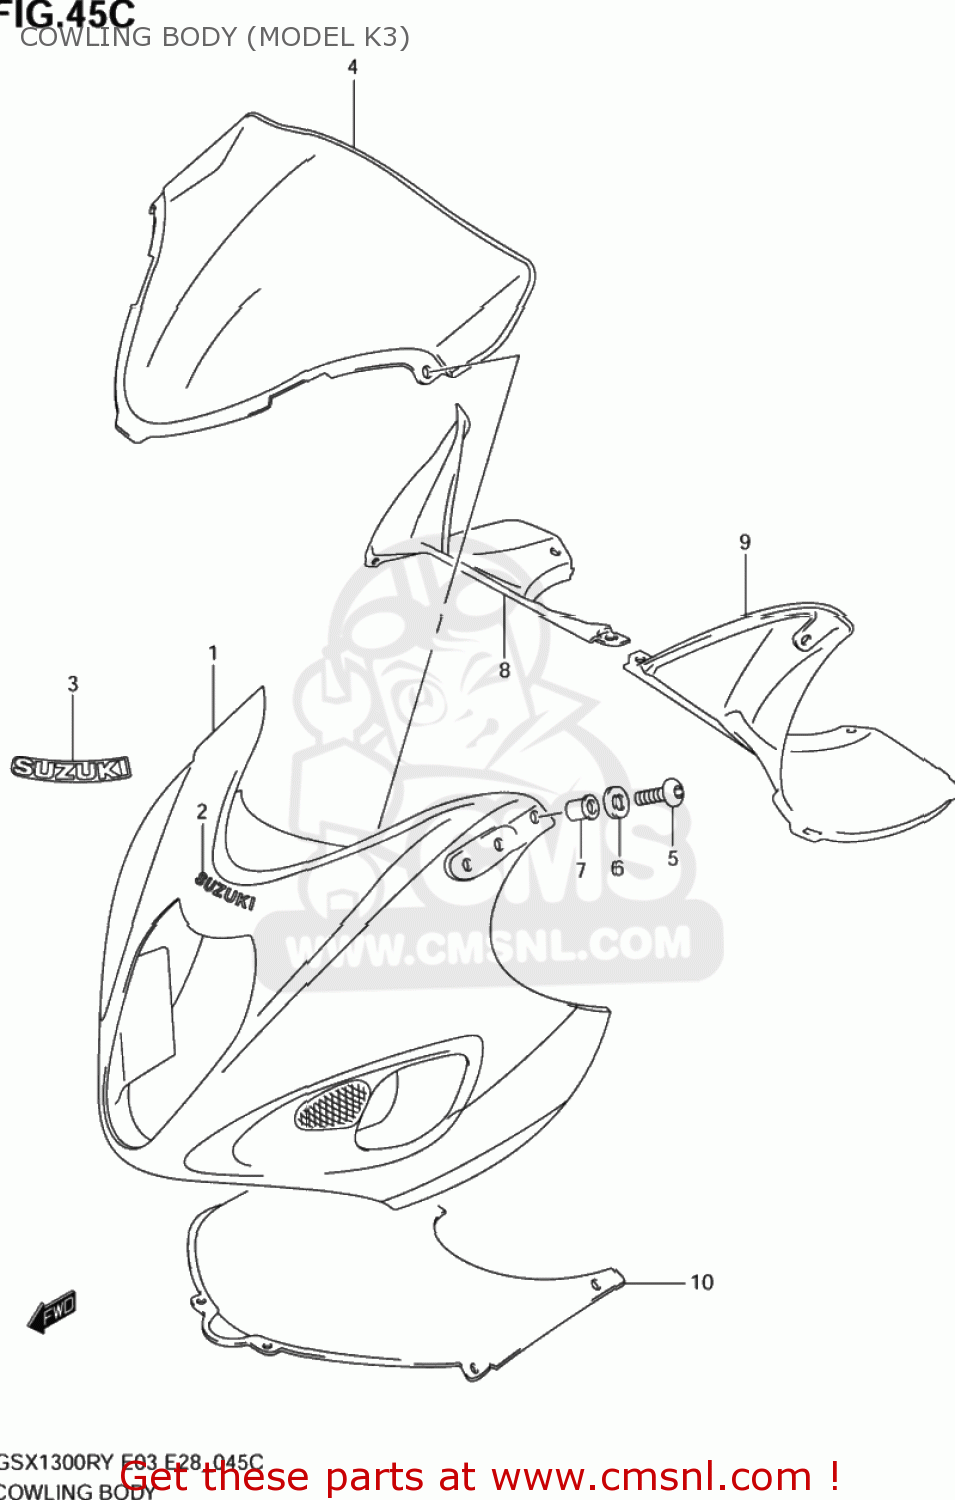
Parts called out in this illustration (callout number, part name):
1	COWLING ASSY,BODY
2	EMBLEM,SUZUKI
3	EMBLEM,SUZUKI
4	WINDSCREEN
5	SCREW(5X14)
6	WASHER
7	NUT
8	PANEL,UPR,R
9	PANEL,UPR,L
10	COVER,BODY COWLING
